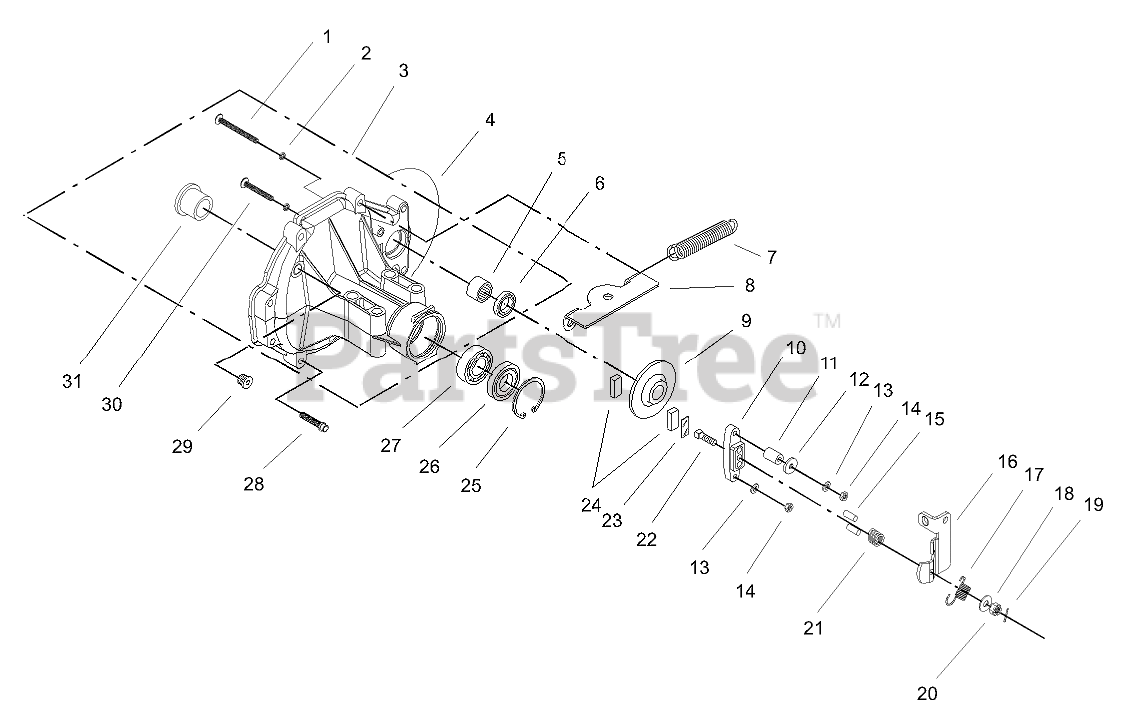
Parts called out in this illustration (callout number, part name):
2	O-RING
3	RH HOUSING ASM
4	SEALANT
5	BEARING-NEEDLE
6	SEAL-LIP
7	SPRING-RETURN
8	BRACKET-CRANK, BELL
9	DISK-BRAKE
10	YOKE-BRAKE
11	SPACER
12	WASHER
13	WASHER-LOCK
15	PIN-BRAKE
16	ARM-BRAKE
17	SPRING-ARM, BRAKE (BIAS)
18	WASHER
19	PIN-COTTER
20	NUT-CASTLE
21	SPRING-BRAKE, ANTI DRAG
22	BOLT-SQH
23	PUCK-PLATE
24	PUCK-BRAKE
25	RING-RETAINING
27	BEARING-BALL
28	SCREW-TTH
29	PLUG-THREAD, STRAIGHT
31	BEARING-FLANGE
